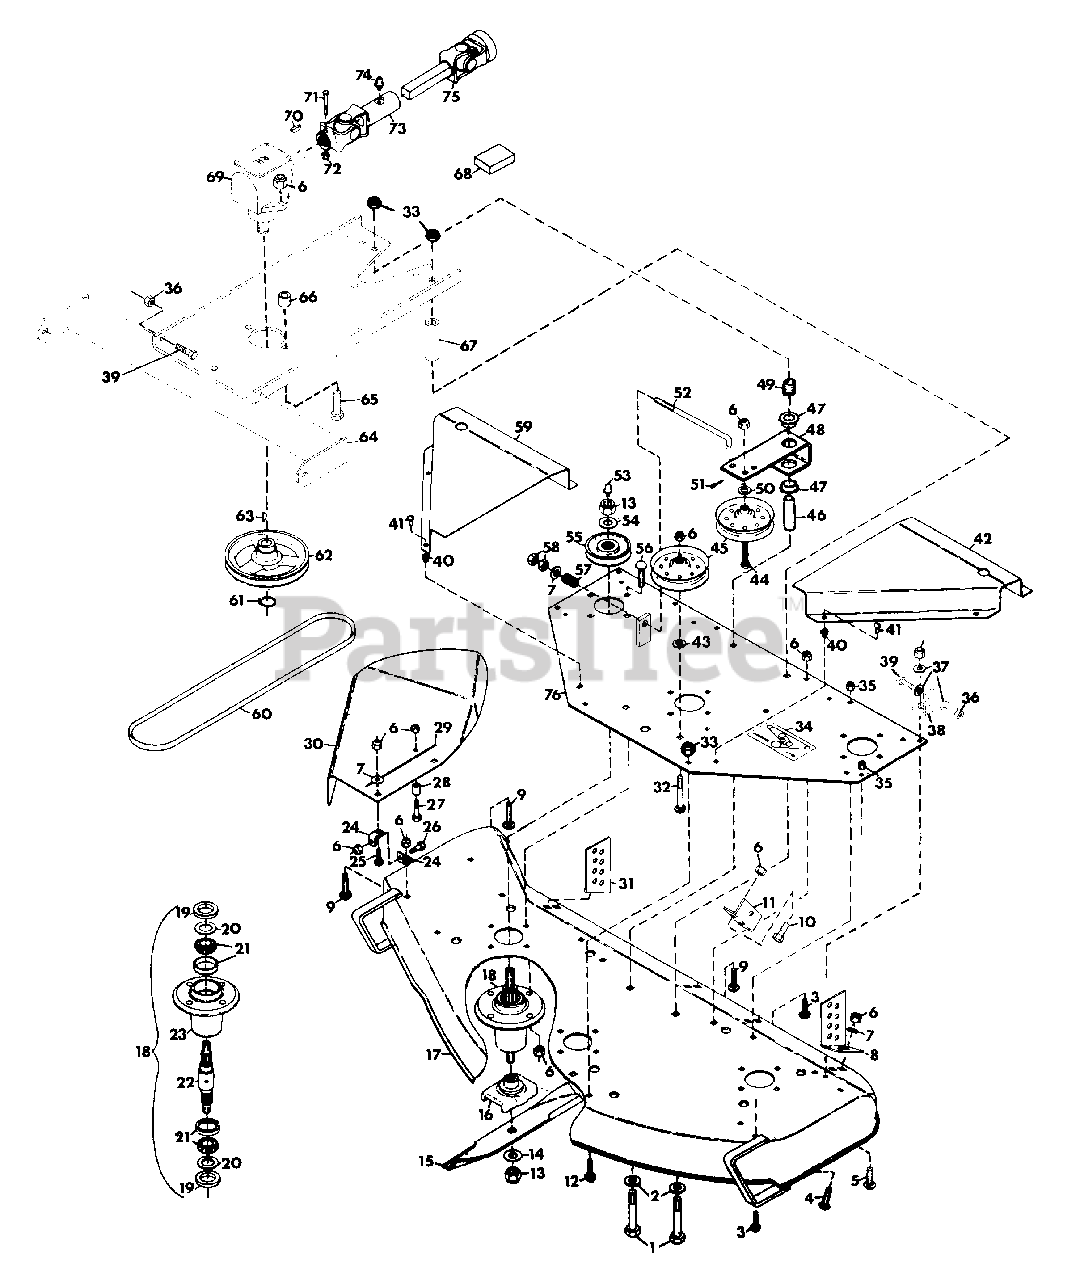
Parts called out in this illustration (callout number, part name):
1	BOLT, HEX 1/2-13X3.75
2	WASHER, FLAT .531X1.062X.095
3	BOLT, CARRIAGE 5/16-18X.75
4	BOLT, HEX 3/8-16X1.25
5	BOLT, CARRIAGE 5/16-18X1.00
6	NUT, LOCK 3/8-16
7	WASHER, FLAT .406X.812X.065
8	PLATE, REAR ADJUSTMENT
9	BOLT, CARRIAGE 3/8-16X.75
10	BOLT, HEX 3/8-16X1.00
11	BRACKET, LIFT
12	BOLT, HEX 1/2-13X1.25
13	NUT, LOCK 5/8-11
14	WASHER, FLAT .656X1.312X.095
15	BLADE
16	WELDMENT, BLADE CRADLE
17	WELDMENT, 50 INCH DECK
18	ASSEMBLY, SPINDLE
19	SEAL, STEEL
20	WASHER, FLAT .975X1.970X.030
21	ASSEMBLY, BEARING
22	SHAFT, SPINDLE
23	HOUSING, BEARING
24	TAB, SPRING
25	BOLT, 3/8-16X1.00 RD HD SQ NK
26	BOLT, HEX 3/8-16X.875
27	BOLT, HEX 3/8-16X1.50
28	STOP, CHUTE
29	STRIPE
30	SHIELD, SAFETY EXTENSION 50 INCH MOWER
31	PLATE, REAR ADJUSTMENT
32	BOLT, 3/8-16X1.75 RD HD SQ NK
33	NUT, LOCK 1/2-13
34	DECAL, BELT INSTALLATION
35	NUT, LOCK 5/16-18
36	NUT, JAM 5/16-18 HEX
37	WASHER, FLAT .344X.688X.065
38	BRACKET, LIFT PIVOT
39	BOLT, HEX 5/16-18X1.50
40	GROMMET, PLASTIC
41	SCREW, MACHINE 1/4-20X.5
42	COVER, PULLEY L.H.
43	WASHER, FLAT .438X1.000X.0832
44	BOLT, HEX 3/8-16X2
45	SHEAVE, IDLER
46	SPACER
47	BUSHING, NYLON .760X1.00X.600
48	ARM, IDLER PIVOT
49	SPRING, COMP.
50	SPACER, IDLER .406X.750X.188
51	PIN, COTTER 3/32X1.00
52	ROD, IDLER
53	FITTING, LUBE 1/8(LEFT AND RIGHT SPINDLE)
53	FITTING, LUBE .125 EXT.(CENTER SPINDLE)
54	WASHER, FLAT .687X1.312X.122/.146
55	SHEAVE, SPINDLE
56	BOLT, 3/8-16X1.25 RD HD SQ NK
57	SPRING, COMP. TYPE 1X.78X338 LB/IN
58	NUT, HEX 3/8-24
59	COVER, PULLEY R.H.
60	BELT, V .500X.312X126.3
61	RING, RETAINING .875 SHAFT
62	SHEAVE, DRIVE
63	KEY, WOODRUFF .250X.875 HARD #A
64	WELDMENT, PLATE SUPPORT
65	BOLT, HEX 3/8-16X2.25
66	SPACER, .375X.100X1.00
67	SPACER, .510X.840X2.43
68	KIT, REPAIR UNIVERSAL JOINT ROCKWELL STD.
68	KIT, REPAIR UNIVERSAL JOINT NEAPCO 1605X
69	GEARBOX, PRO MASTER-50
70	KEY, WOODRUFF .187X.75 HARD #9
71	BOLT, HEX 1/4-20X2.00
72	NUT, LOCK 1/4-20
73	ASSEMBLY, U-JOINT
74	FITTING, LUBE 1/4-28
75	SHAFT, PROP. SQ. BAR
76	WELDMENT, SUPPORT PLATE
NS	ASM., PRO MASTER-50 DRIVE
NS	DECAL, DANGER HAND
NS	DECAL, DANGER FOOT
NS	DECAL, WARNING EYE
NS	DECALS, PRO MASTER-50
